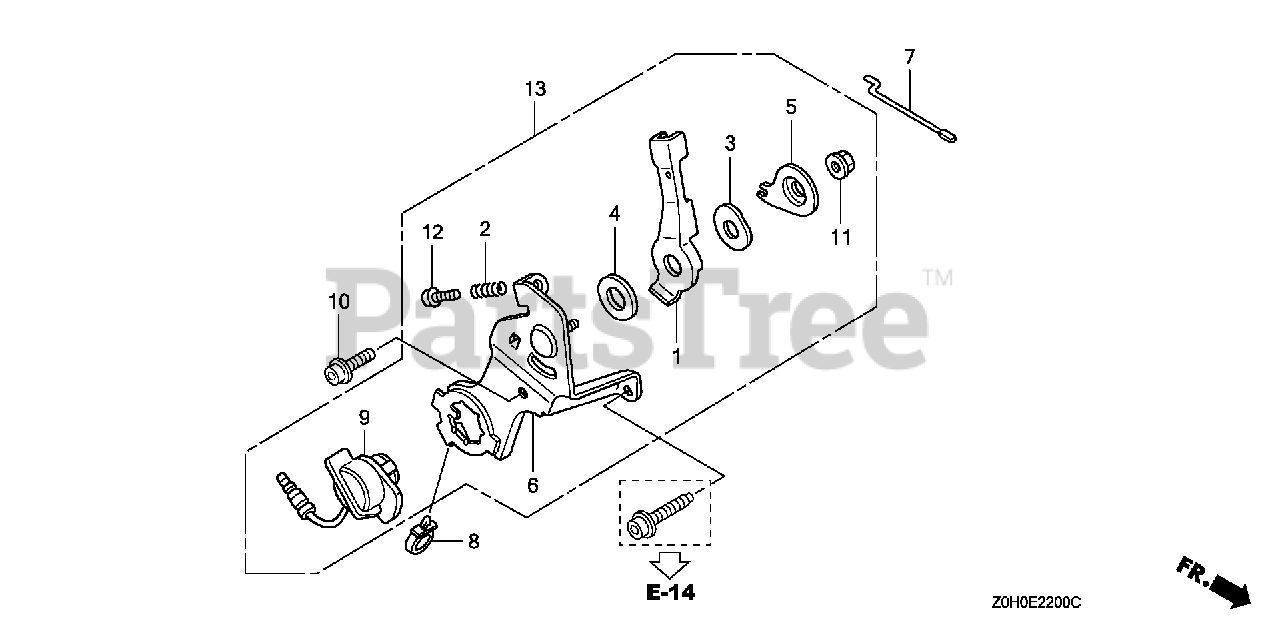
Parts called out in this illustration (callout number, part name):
1	LEVER, CONTROL
2	SPRING, CONTROL ADJUSTING
3	SPRING, LEVER
4	SPACER, CONTROL LEVER
5	WASHER, CONTROL LEVER
6	BASE, CONTROL
7	ROD, THROTTLE
8	CLIP, IGNITION WIRE (8MM)
9	SWITCH ASSY., ENGINE STOP
10	BOLT, SOCKET (5X10)
11	NUT, SELF-LOCK (6MM)
12	SCREW, PAN (5X25)
13	CONTROL ASSY.
